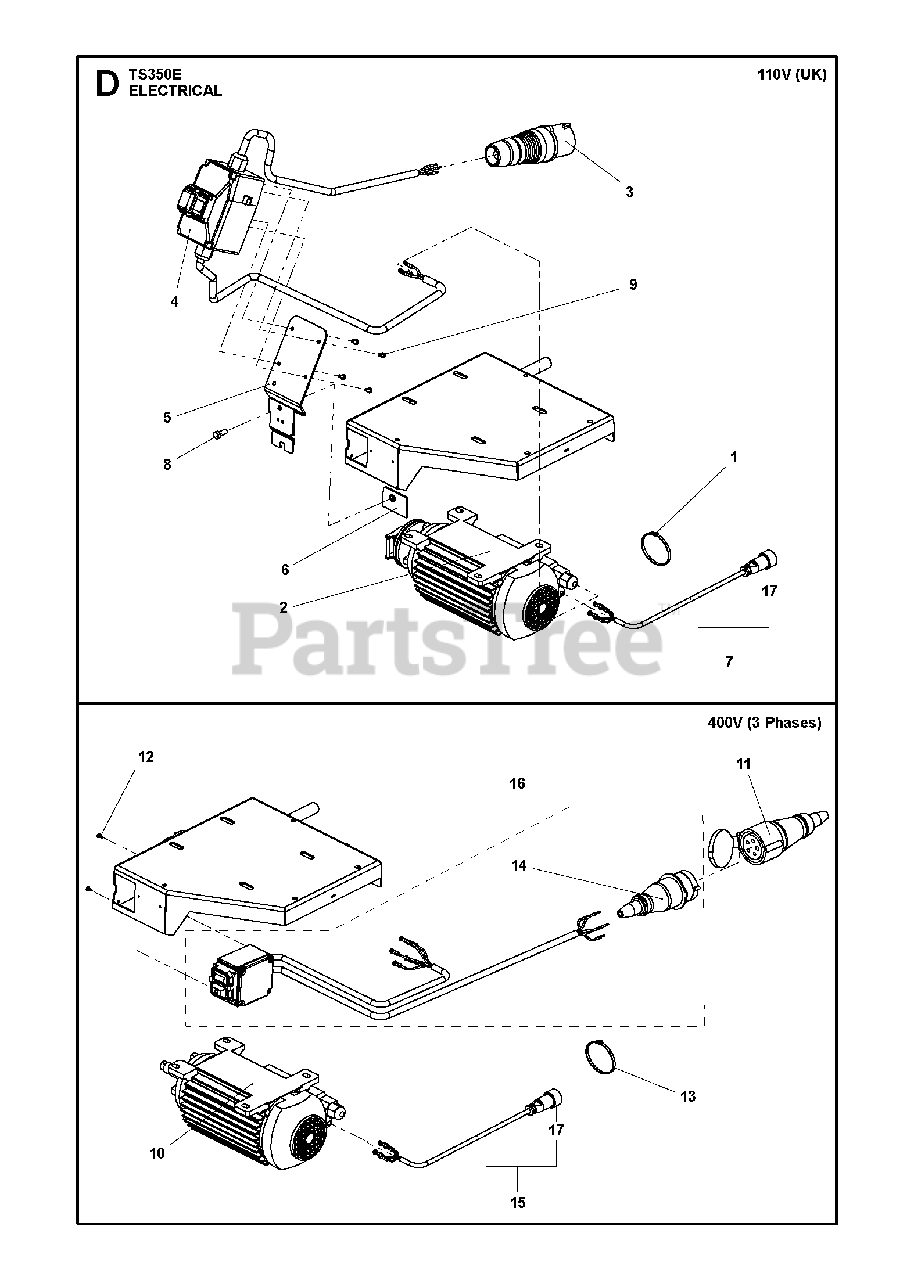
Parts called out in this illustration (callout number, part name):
3	FICHE 2P+T 32A 110V 4H/PRESSE
6	TOLE DE SERRAGETS350F
9	SCREW EHHM
11	PROLONG. 3P+N+T 16A 6H/
12	SCREW CRPANT
14	FICHE 16A 380V 3P+N+T 6H/AVEC
